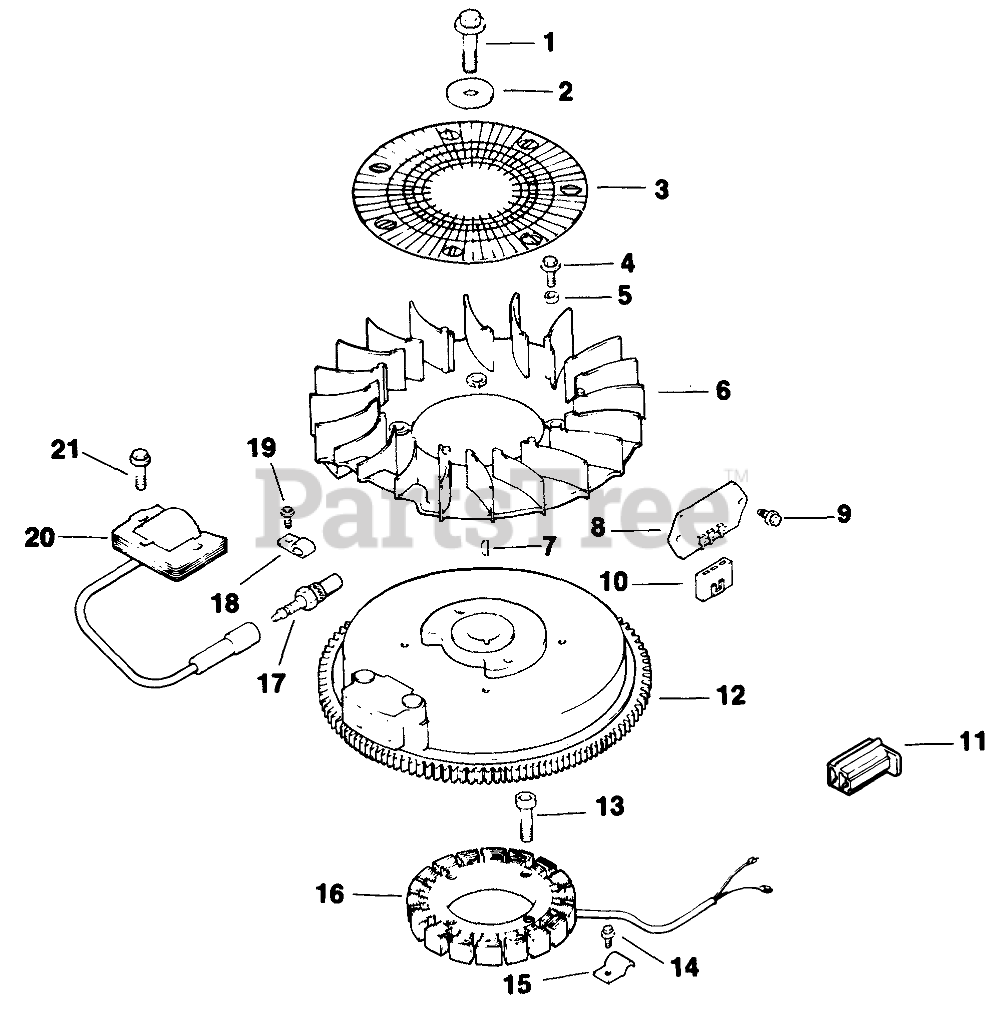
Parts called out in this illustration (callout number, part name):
1	Screw
2	Washer-Flat
3	Screen-Grass
4	Screw
5	Spacer-Fan
6	Fan
7	Key
8	Rectifier-Unrelated
9	Screw
10	Connector
11	Connector
12	Flywheel
13	Screw
15	Clip
16	Stator 15 amp.
17	Spark Plug
18	Clip
20	Module-Ignition
21	Screw
